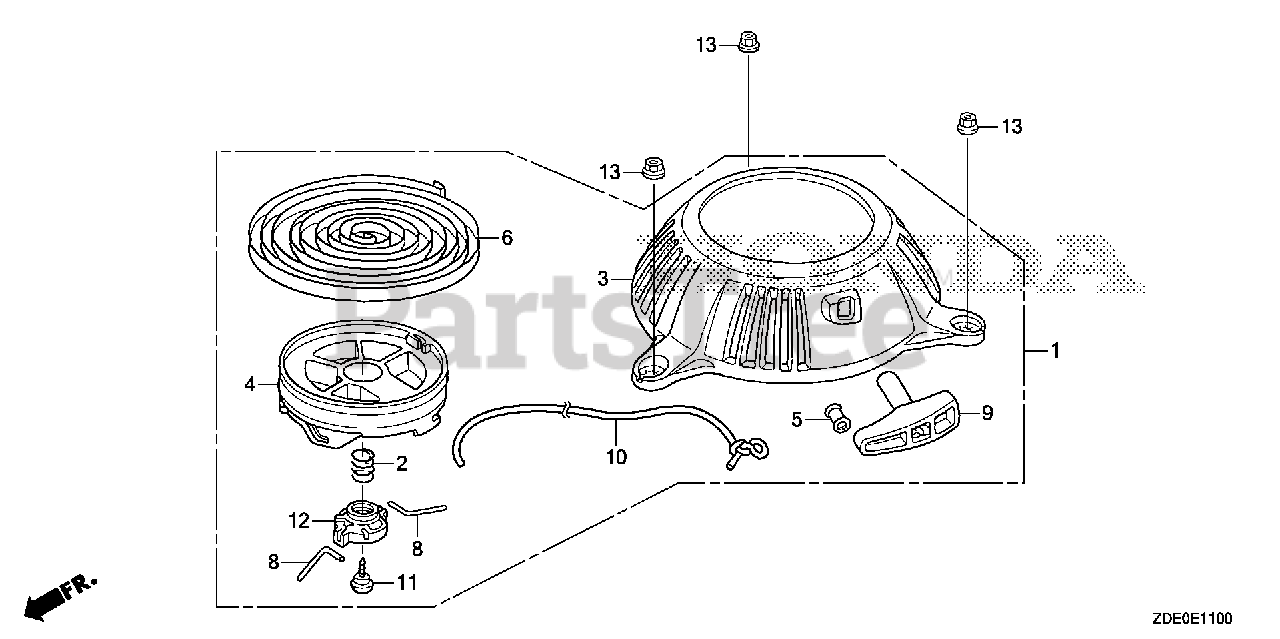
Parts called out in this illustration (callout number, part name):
1	STARTER ASSY., RECOIL
2	SPRING, FRICTION
3	CASE, RECOIL STARTER
4	REEL, RECOIL STARTER
5	GUIDE, ROPE
6	SPRING, RECOIL STARTER
9	KNOB, RECOIL STARTER
10	ROPE, RECOIL STARTER
11	SCREW, SETTING
13	NUT, FLANGE (5MM)
